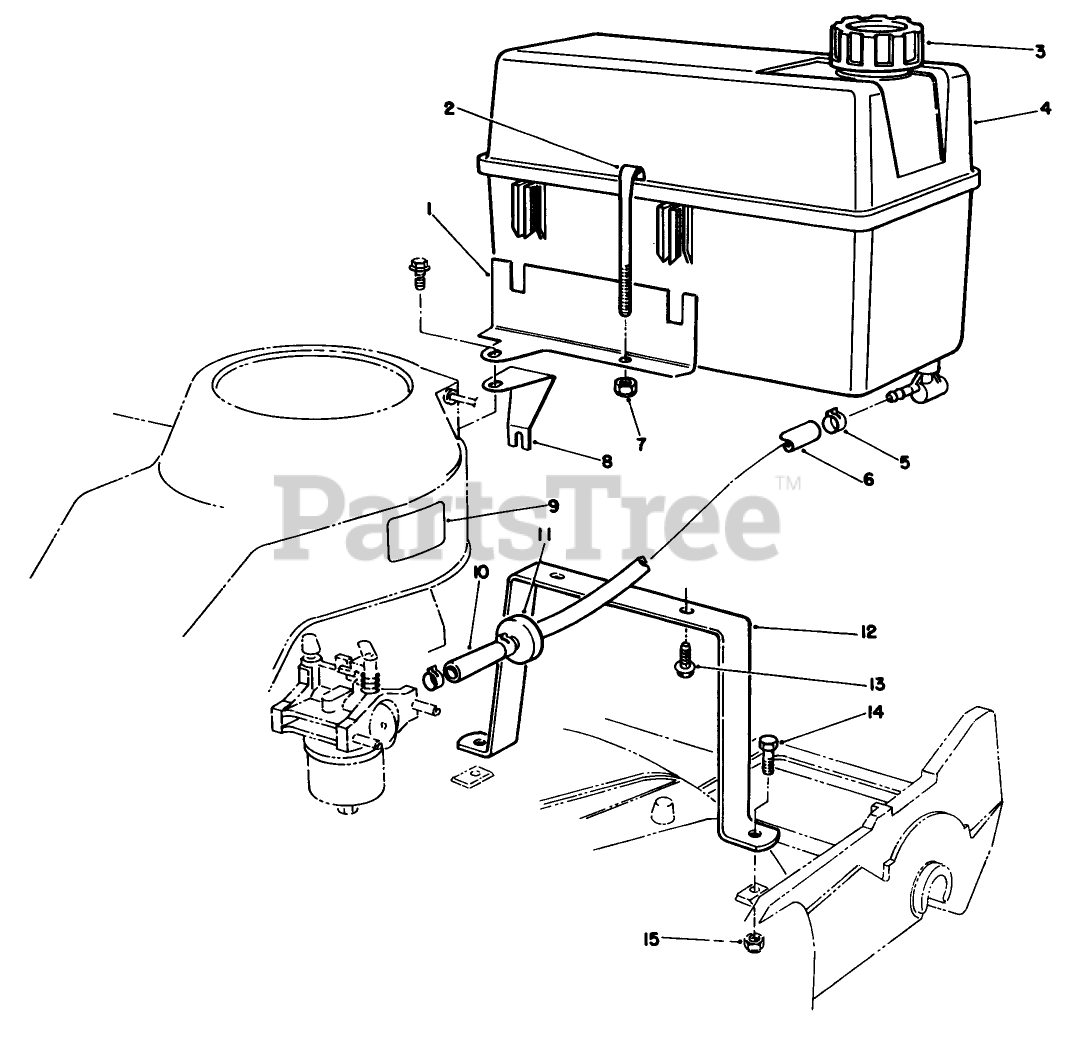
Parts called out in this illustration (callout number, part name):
2	RETAINER - FUEL TANK
3	GAS CAP ASM
5	CLAMP-FUEL LINE
6	HOSE-FUEL
7	NUT-LOCK, NI
9	DECAL - FUEL
10	HOSE-FUEL
11	FILTER-FUEL
13	SCREW-HWH
14	SCREW-HH
15	NUT-LOCK, NI
